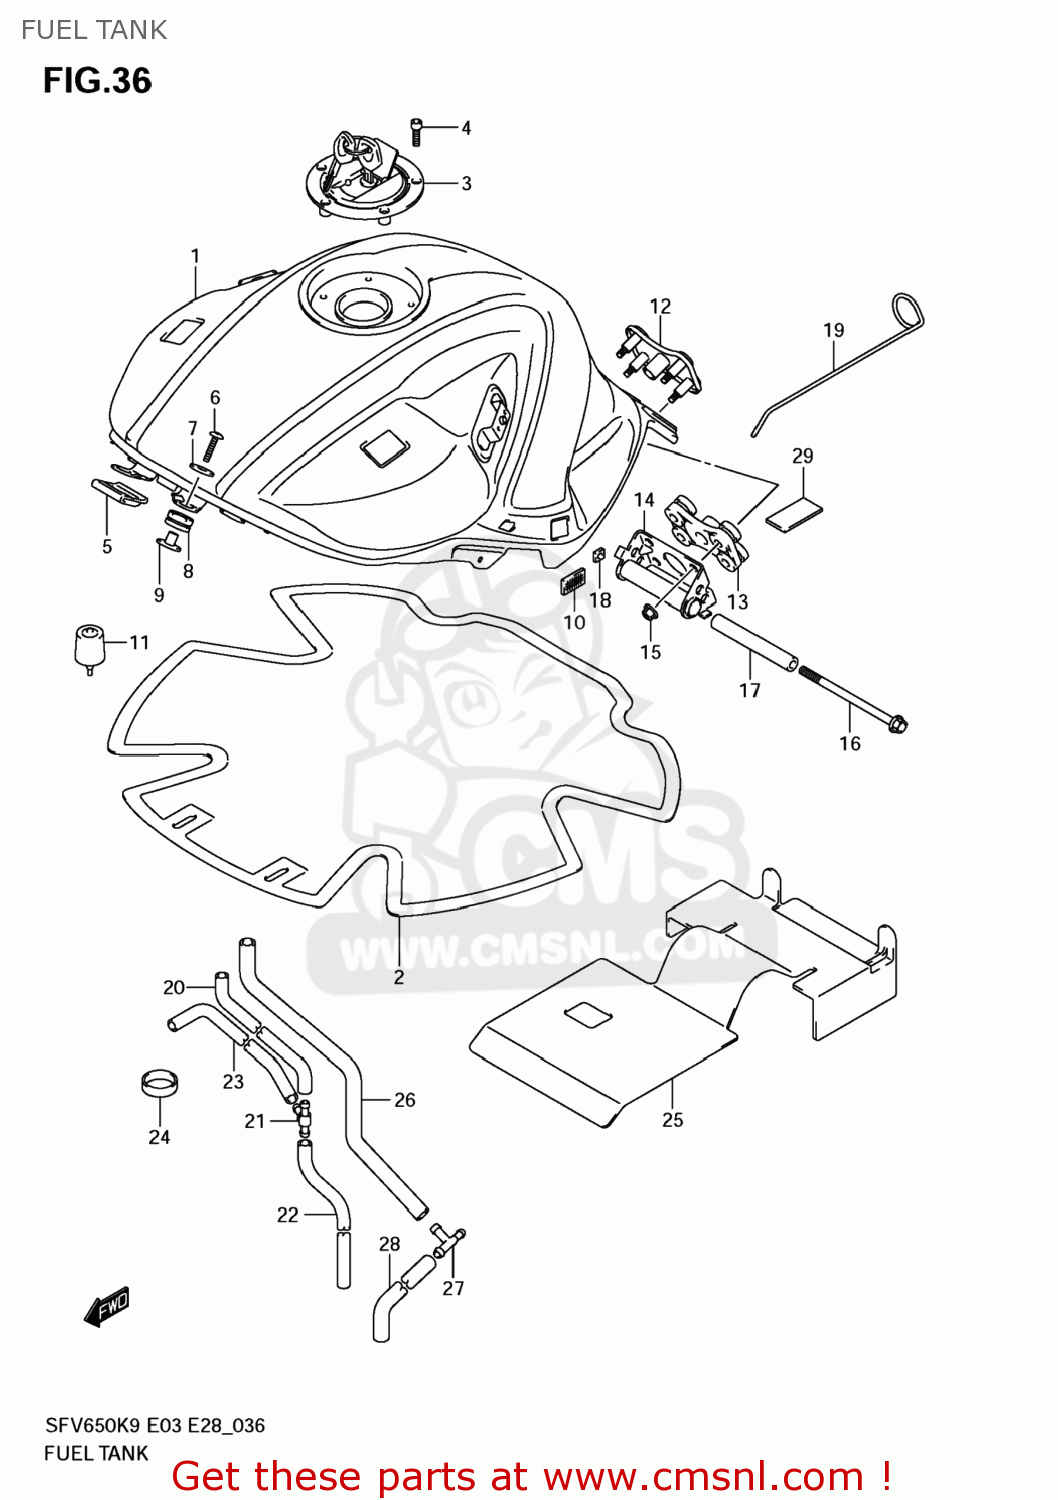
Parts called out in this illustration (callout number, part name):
1	TANK ASSY,FUEL
2	SHIELD,FUEL TANK HEAT
3	CAP SET,FUEL TANK
4	BOLT(5X20)
5	RUBBER,FUEL TANK FR
6	SCREW(6X25)
7	WASHER(6.5X22X1.6)
8	CUSHION,FUEL TANK FR
9	SPACER,FUEL TANK FR
10	FASTENER,FRAME COVER
11	CUSHION,FUEL TANK RR
12	BRACKET,FUEL TANK RR UP
13	CUSHION,FUEL TANK RR
14	BRACKET,FUEL TANK RR
15	NUT
16	BOLT(6X100)
17	SPACER,FUEL TANK RR
18	NUT
19	STAY,FUEL TANK
20	HOSE,FUEL TANK BREATHER NO.1
21	3 WAY
22	HOSE(5X8.2X600)
23	HOSE,VACUUM
24	HOSE(12X16X600)
25	SHEET,HEAT SHIELD RUBBER
26	HOSE,FUEL TANK WATER DRAIN
27	3 WAY
28	HOSE,WATER DRAIN
29	PROTECTOR(30X30X3)
